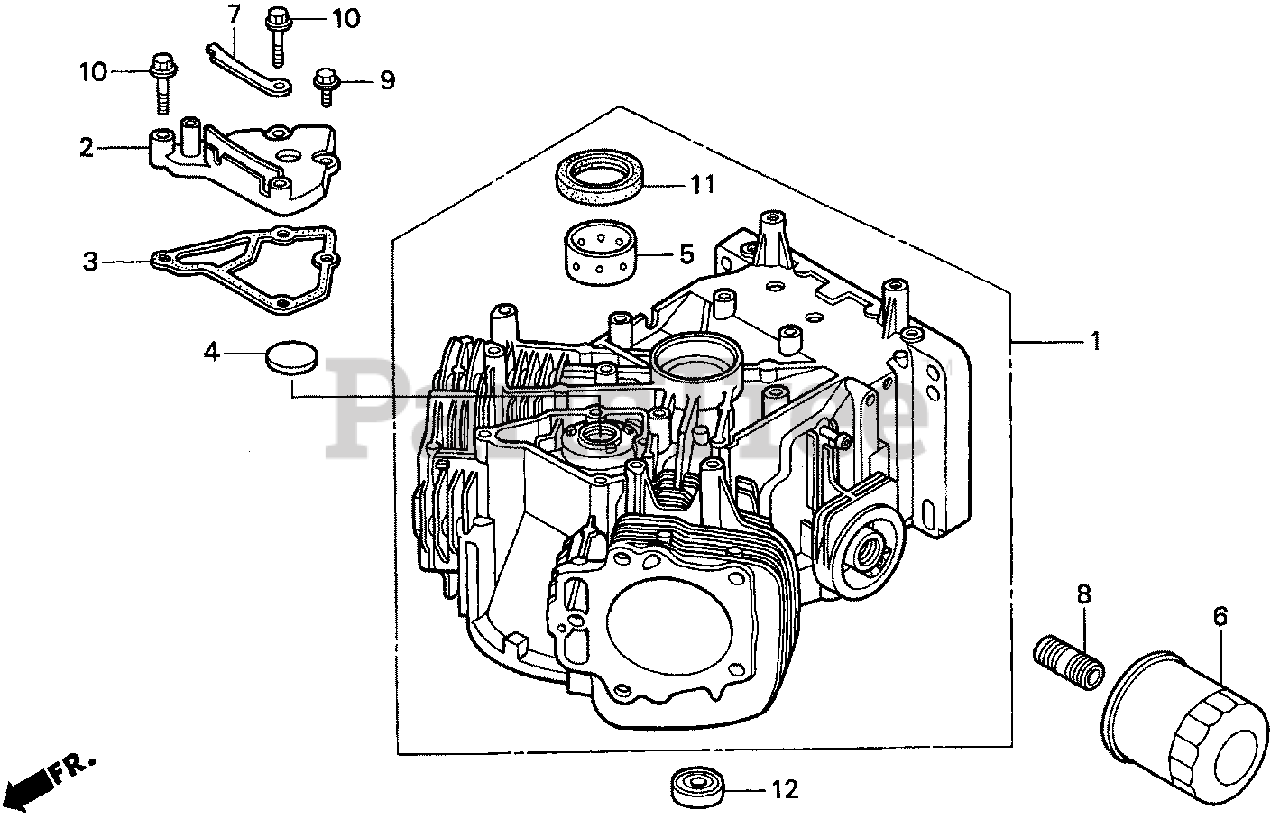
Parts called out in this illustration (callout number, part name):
1	CYLINDER ASSY.
2	COVER, BREATHER
3	GASKET, BREATHER COVER
4	VALVE, BREATHER
5	BEARING A, MAIN (TO SELECT CORRECT BEARING, SEE THE SERVICE MANUAL.)
5	BEARING B, MAIN (TO SELECT CORRECT BEARING, SEE THE SERVICE MANUAL.)
5	BEARING C, MAIN (TO SELECT CORRECT BEARING, SEE THE SERVICE MANUAL.)
6	FILTER, OIL (SOLD INDIVIDUALLY)
6	FILTER, OIL (SOLD IN MULTIPLES OF 30)
7	CLAMP, WIRE
8	HOLDER, OIL FILTER
9	BOLT, FLANGE (6X16)
10	BOLT, FLANGE (6X32)
11	OIL SEAL (38X58X11)
12	BEARING, RADIAL BALL (6003)
